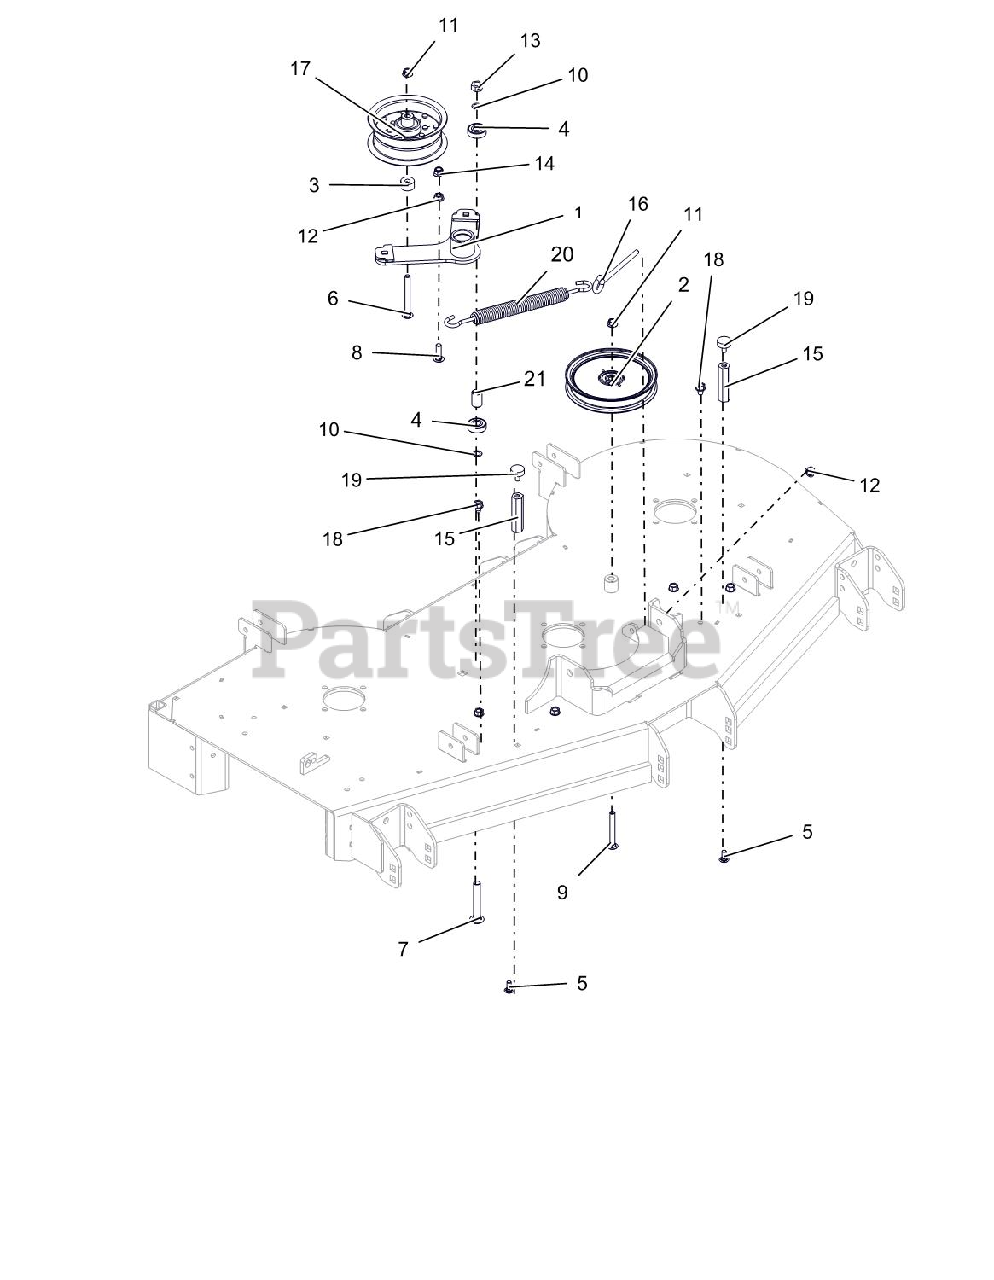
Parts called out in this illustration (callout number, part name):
1	WLDMT, DECK IDLER ARM
2	IDLER, FLAT-6.00" X .75"
3	SPACER .390X1.000X.562
4	BRG-BALL .500X1.38X.437
5	BLT,RDHDSQNK .31-18X.75 LOCTIT
6	@BLT-RHDSSQNK .38-16X3.50 G5YZ
7	BLT,RDHDSQSHNK.50-13X3.25 G5YZ
8	@BLT-RHDSSQNK .38-16X1.25 G5YZ
9	@BLT-RDHDSQNK .38-16X3.00 G5YZ
10	WASHER, .500X.750X.020 THRUST
11	NUT-LK-CTR-FLG .38-16 YWZC
12	@NUT-SPNLK-FLG .375-16 YWZC
13	@NUT-LK-CTR .50-13 YWZC
14	@NUT-LK-NYL-FLG .38-16 YWZC
15	NUT, COUPLING .31-18 X 3.00
16	BOLT,.38-16 X 4.25-.62 DIA EYE
17	PULLEY, FLAT 5.00X2.36X.375
18	@SCR-TAP .38-16X.50 HWH TR YWZ
19	BUMPER, RUBBER
20	SPRING, EXTENSION
21	SPACER .510 X .75 X 1.1485
